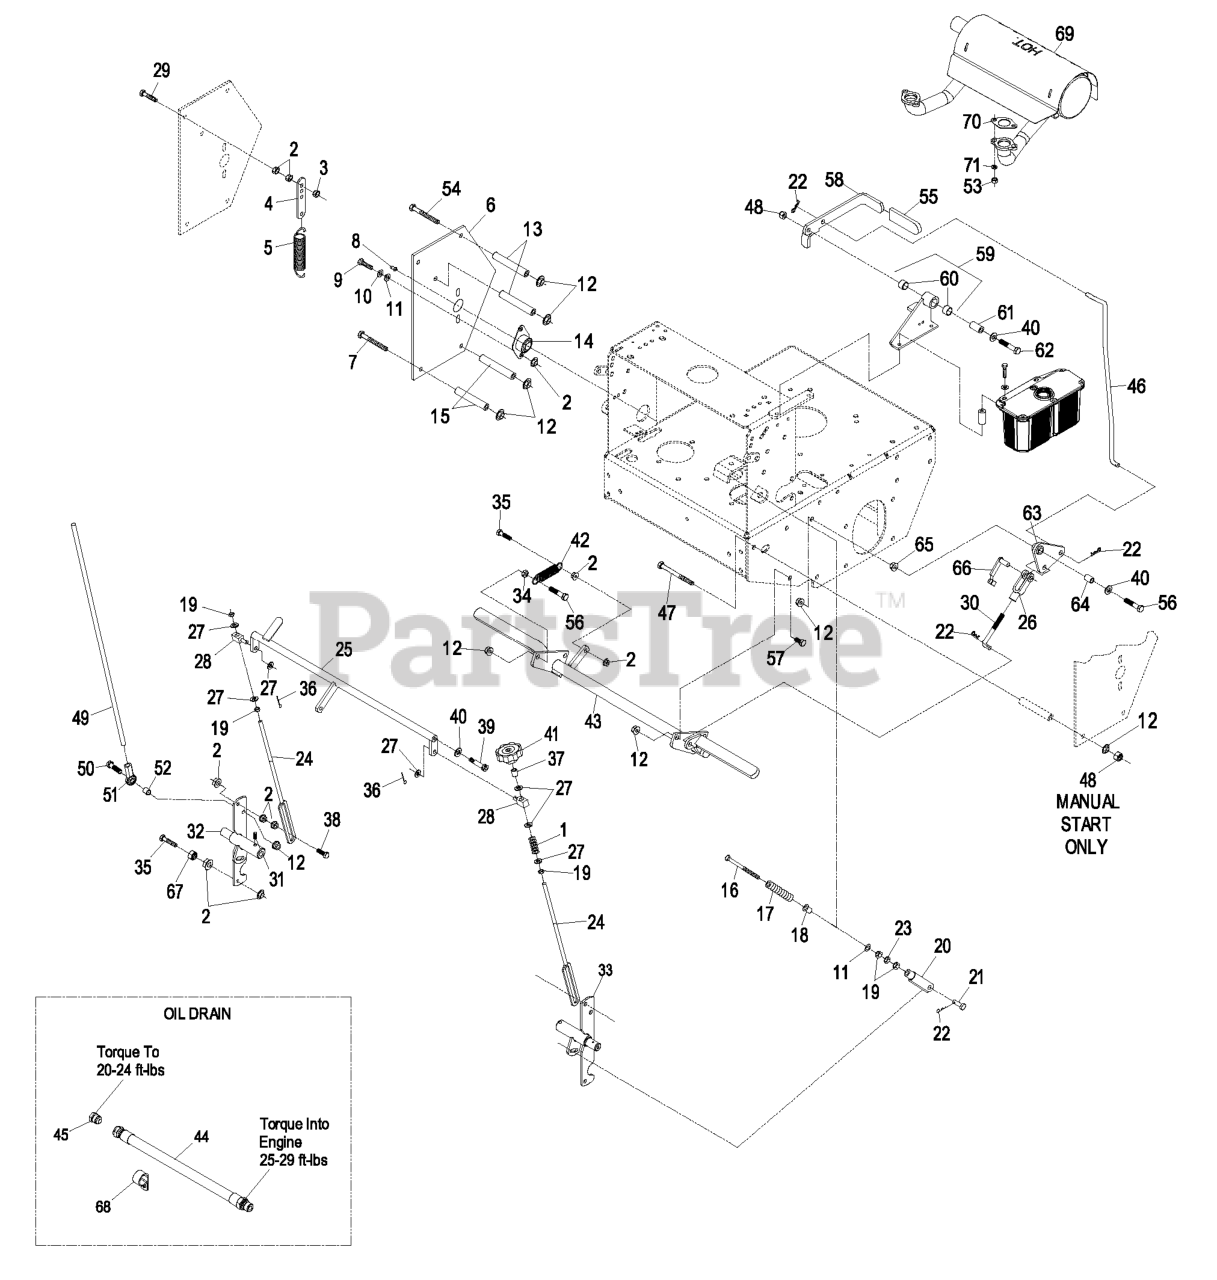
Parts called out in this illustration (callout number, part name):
1	SPRING-COMPRESSION
3	NUT-LOCK, NI
4	TAB-SPRING, EXTENSION
5	SPRING-EXTENSION
6	SHIELD-CONTROL
7	SCREW-HH
8	FITTING-GREASE
9	SCREW-HH
10	WASHER-LOCK
11	WASHER-FLAT
12	NUT-HHF, WHIZ
13	SPACER-SHIELD
14	BEARING-FLANGE, SIDE
15	SPACER-SHIELD
16	BOLT-RETURN, NEUTRAL
17	SPRING,COMPRESSION (NEUT)
18	BUSHING-FLANGED
19	NUT-HEX
20	YOKE-ADJUSTABLE
21	PIN-CLEVIS
22	PIN-COTTER
23	NUT-JAM
24	LINK-CONTROL, SPEED
25	CRANK-CONTROL, SPEED
26	YOKE-LINKAGE, BRAKE
27	WASHER-PLAIN
29	BOLT-TAP, HH
30	LINKAGE-LOWER
31	SCREW-SET
32	SHAFT-CONTROL, LH
33	SHAFT-CONTROL, RH
34	NUT-JAM
35	SCREW-HH
36	PIN-COTTER
38	SCREW-HH
39	SCREW-HSH
40	WASHER-FLAT
41	KNOB-TRACKING
42	SPRING-IDLER
46	LINKAGE,UPPER- TTHP
47	SCREW-HH
48	NUT-LOCK, NI
49	LINK,DRIVE (PLTD)
50	SCREW-HH
51	JOINT-BALL END, LH
52	SPACER-TUBE, PUMP LINK
54	SCREW-HH
55	GRIP-LEVER
56	SCREW-HH
57	SCREW-HH
58	LEVER,PARK BRK W/DECAL
59	BRACKET ASM
60	SLEEVE-BUSHING
61	BUSHING-PIVOT
62	SCREW-HH
63	BELLCRANK ASM
64	BUSHING-PLASTIC
66	PIN-SPRING, CLEVIS
67	NUT-JAM
68	CLIP-LOOM
70	GASKET-EXHAUST
71	WASHER-LOCK
